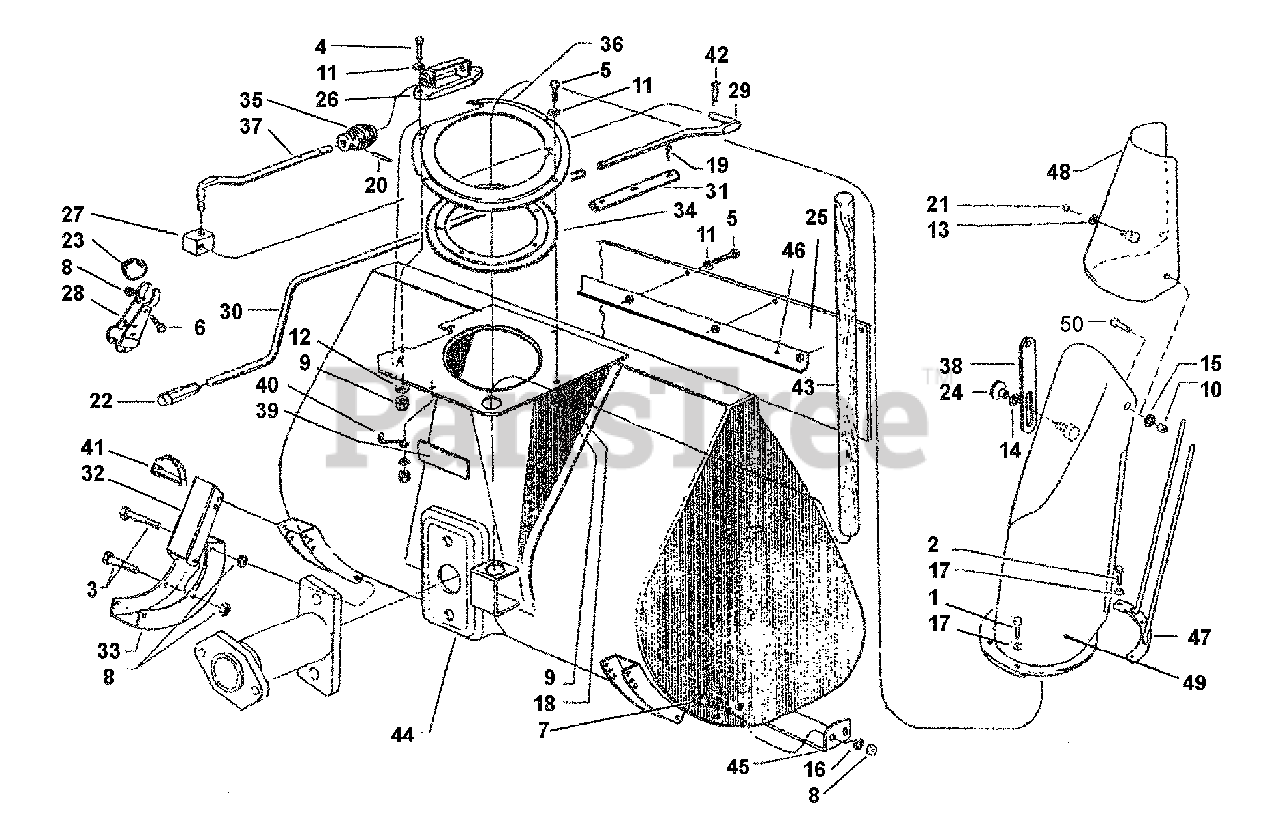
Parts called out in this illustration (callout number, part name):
1	CAPSCREW, M6X10
2	CAPSCREW, M6X14
3	CAPSCREW, TE M6X55
4	CAPSCREW, M6X25
5	CAPSCREW, M6X16
6	CAPSCREW, M6X20
7	BOLT, M6X16
8	LOCKNUT, M6, STANDARD
9	LOCKNUT, M6, DEFORMED
10	LOCKNUT, M10, DEFORMED
11	WASHER, FLAT, M6 4X12
12	WASHER, FLAT, M6 6X18
13	WASHER, FLAT, M9X17X1 6
14	WASHER, FLAT, M10.5X18
15	WASHER, FLAT, M10.5X21
16	WASHER, FLAT, M6 4
17	WASHER, SUPER, M6
18	WASHER, LOCK, M6 4
19	PIN COTTER, A 3X20
20	PIN SPLIT, SW 3X22 SPIROL
23	HANDLE GUIDE
24	RING INSP DOOR
25A	MUDFLAP 28"
25B	MUDFLAP 24"
25C	MUDFLAP 20"
26	SUPPORT SCREW
27	METAL BLOCK
28	BRACKET HANDLE GUIDE
29	CONTROL ROD
30	CONTROL ROD
37	ROD EXTENSION
44A	CRANKCASE 28"
44B	CRANKCASE 24"
44C	CRANKCASE 20"
46A	MUDFLAP STOP 28"
46B	MUDFLAP STOP 24"
46C	MUDFLAP STOP 20"
50	CAPSCREW, M10X16
